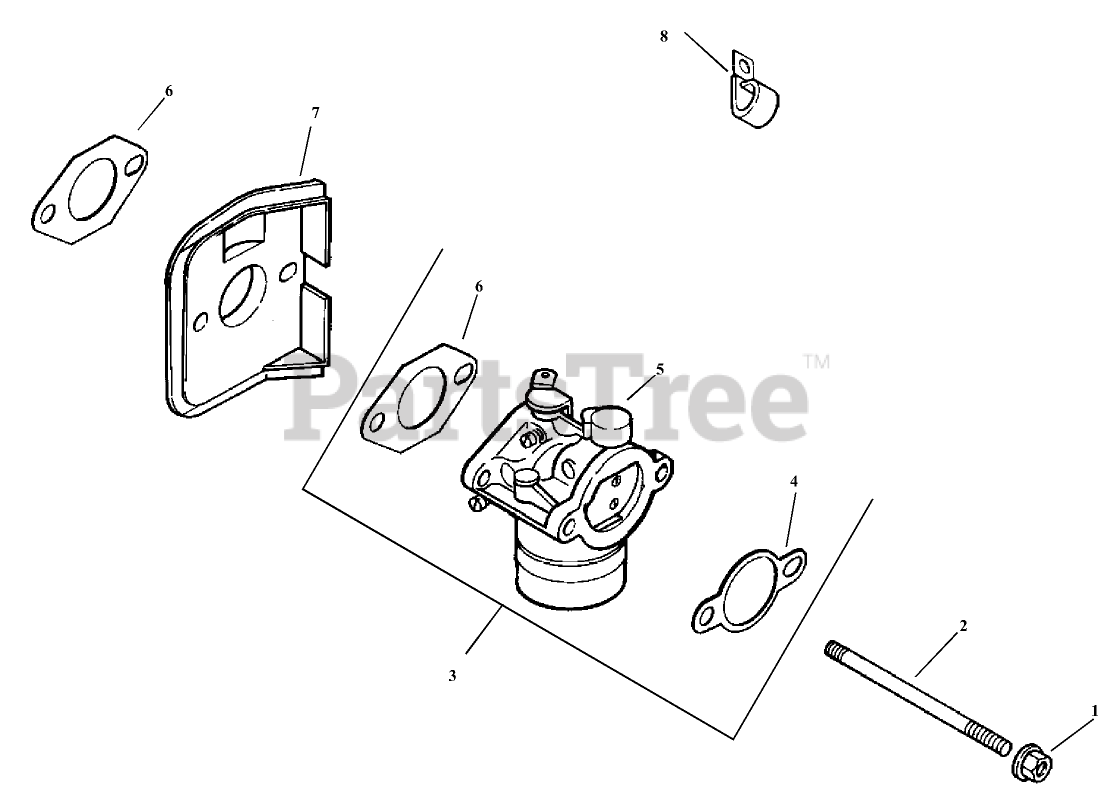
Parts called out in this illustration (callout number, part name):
1	NUT-FLANGE (M6X1.0)
2	Stud (M6x1.0x116)
3	Kit-Carburetor w/Gaskets (Incl. 4-6)
4	Gasket-Base, Air Cleaner
5	Carburetor ASM
6	Gasket-Carburetor
7	Deflector-Heat
8	CLIP-CABLE
